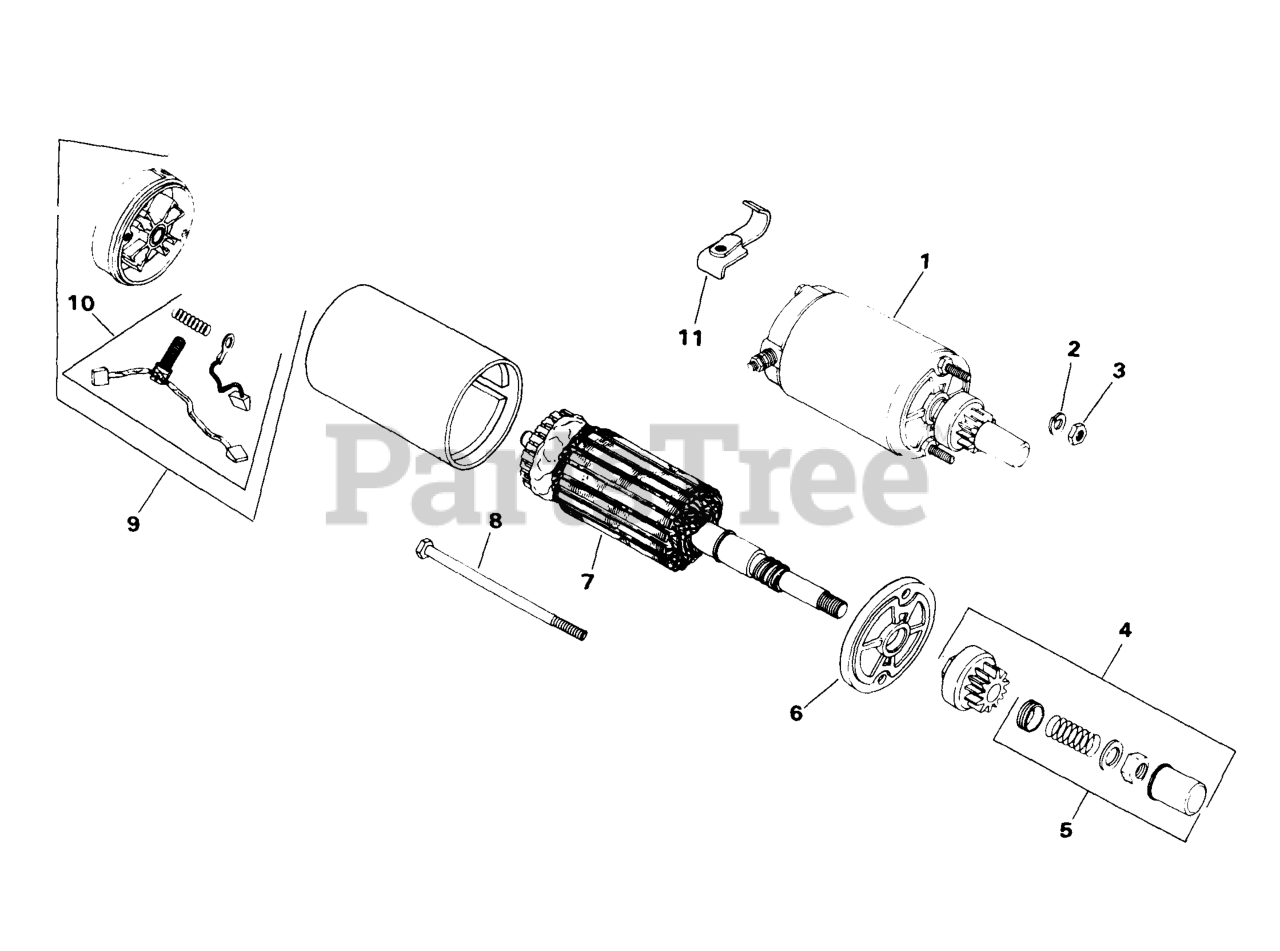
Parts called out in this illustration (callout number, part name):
1	Starter Assembly
2	Washer, Lock 1/4"
3	Nut, Hex. 1/4-20
4	Kit, Drive
5	Kit, Drive Parts
6	Cap, Drive End
7	Armature
8	Bolt, Thru 1/4-20x5-7/8"
9	Cap Assembly, Commutator End
10	Kit, Brush & Spring
